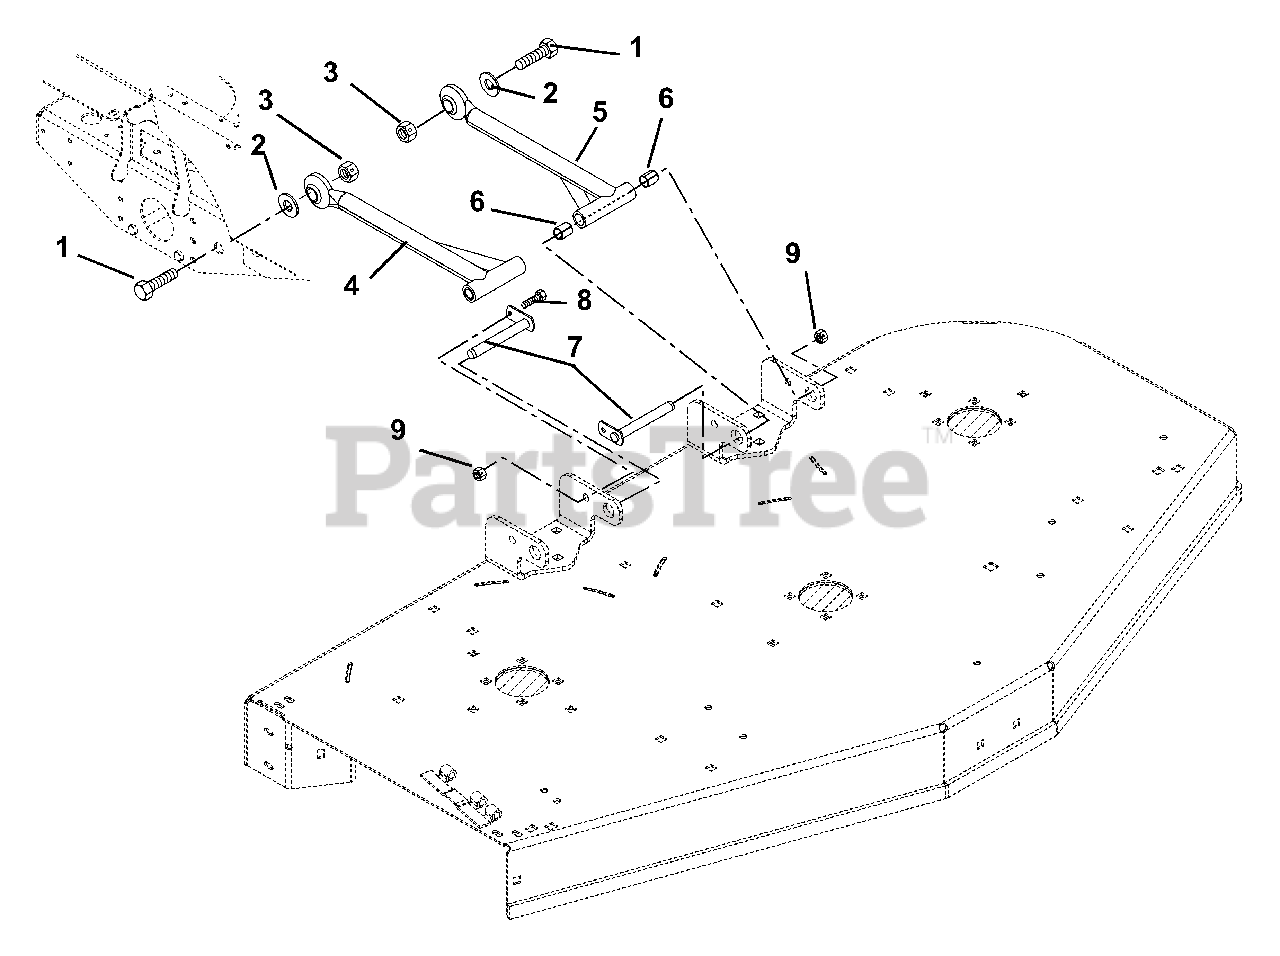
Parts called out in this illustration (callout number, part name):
1	Bolt, Hex .875-9 x 3.00
2	Bushing, Sleeve .875 x 1.25 x .531
3	Nut, Locking Center .875-9
4	Assembly, Mower Mounting
5	Arm, Mower Mounting
6	Bearing, .75 x .875 x 1.00
7	Weldment, Mower Mounting Pin
8	Bolt, Hex .38-16 x 1.00
9	Nut, Nyloc Flange 3/8-16
